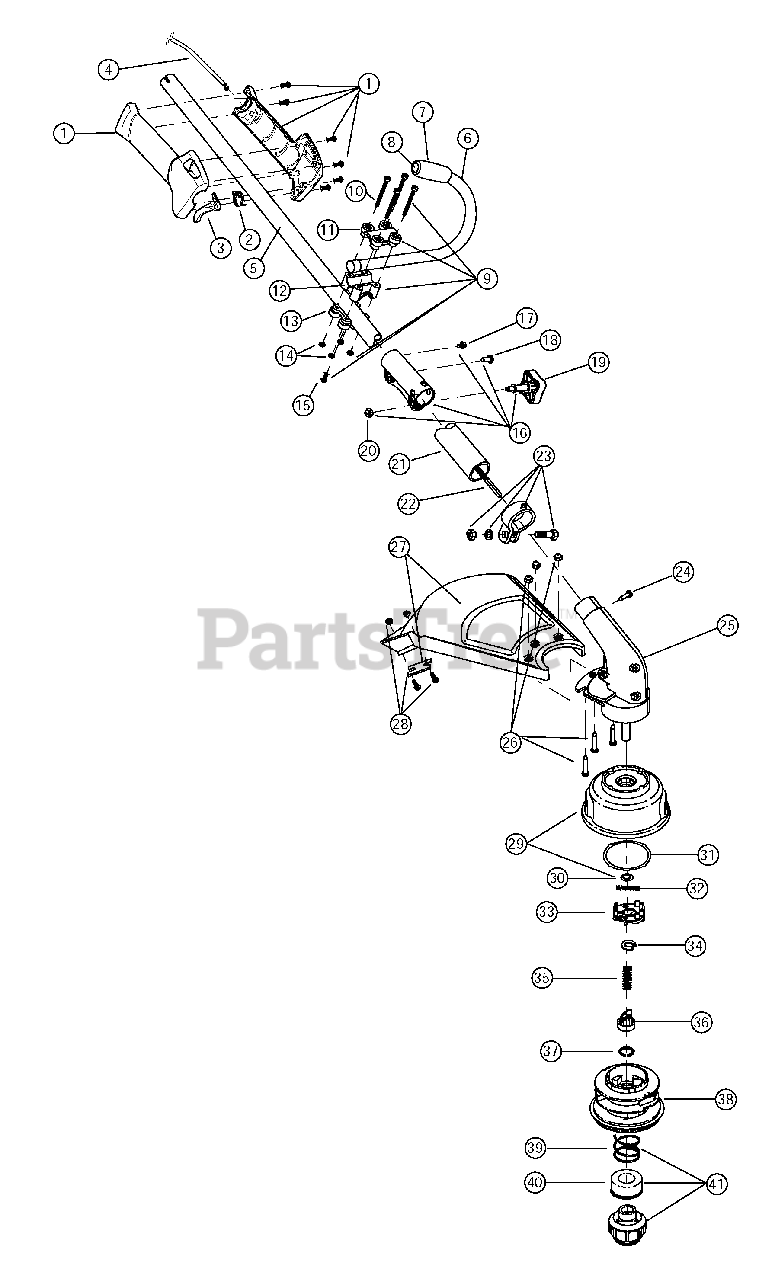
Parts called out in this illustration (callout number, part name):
1	Throttle Housing and Trigger Assembly
2	Throttle Trigger Spring
3	Throttle Trigger
4	Throttle Cable Assembly
5	Upper Drive Shaft Housing Assembly
6	J-Handle Assembly
8	Tube Closure
9	Handle Bracket Assembly
11	Upper Handle Clamp
12	Middle Handle Clamp
13	Lower Handle Clamp
15	Anti-Rotation Screw
16	EZ-Link Coupler
19	Adjustment Knob
20	Knob Retaining Nut
21	Lower Drive Shaft Housing Assembly
22	Lower Flexible Drive Shaft
23	Lower Clamp Assembly
24	Anti-Rotation Screw
25	Gearbox Assembly
26	Shield Mounting Hardware
27	Shield and Blade Assembly
28	Blade Assembly
29	Outer Spool and Eyelet Assembly
30	Retainer
31	Thrust Washer
32	Small Spring
33	Slider
36	Plunger
38	Inner Reel
39	Large Spring
40	Foam Seal
41	Bump Head Knob Assembly with Spring and Foam Seal
